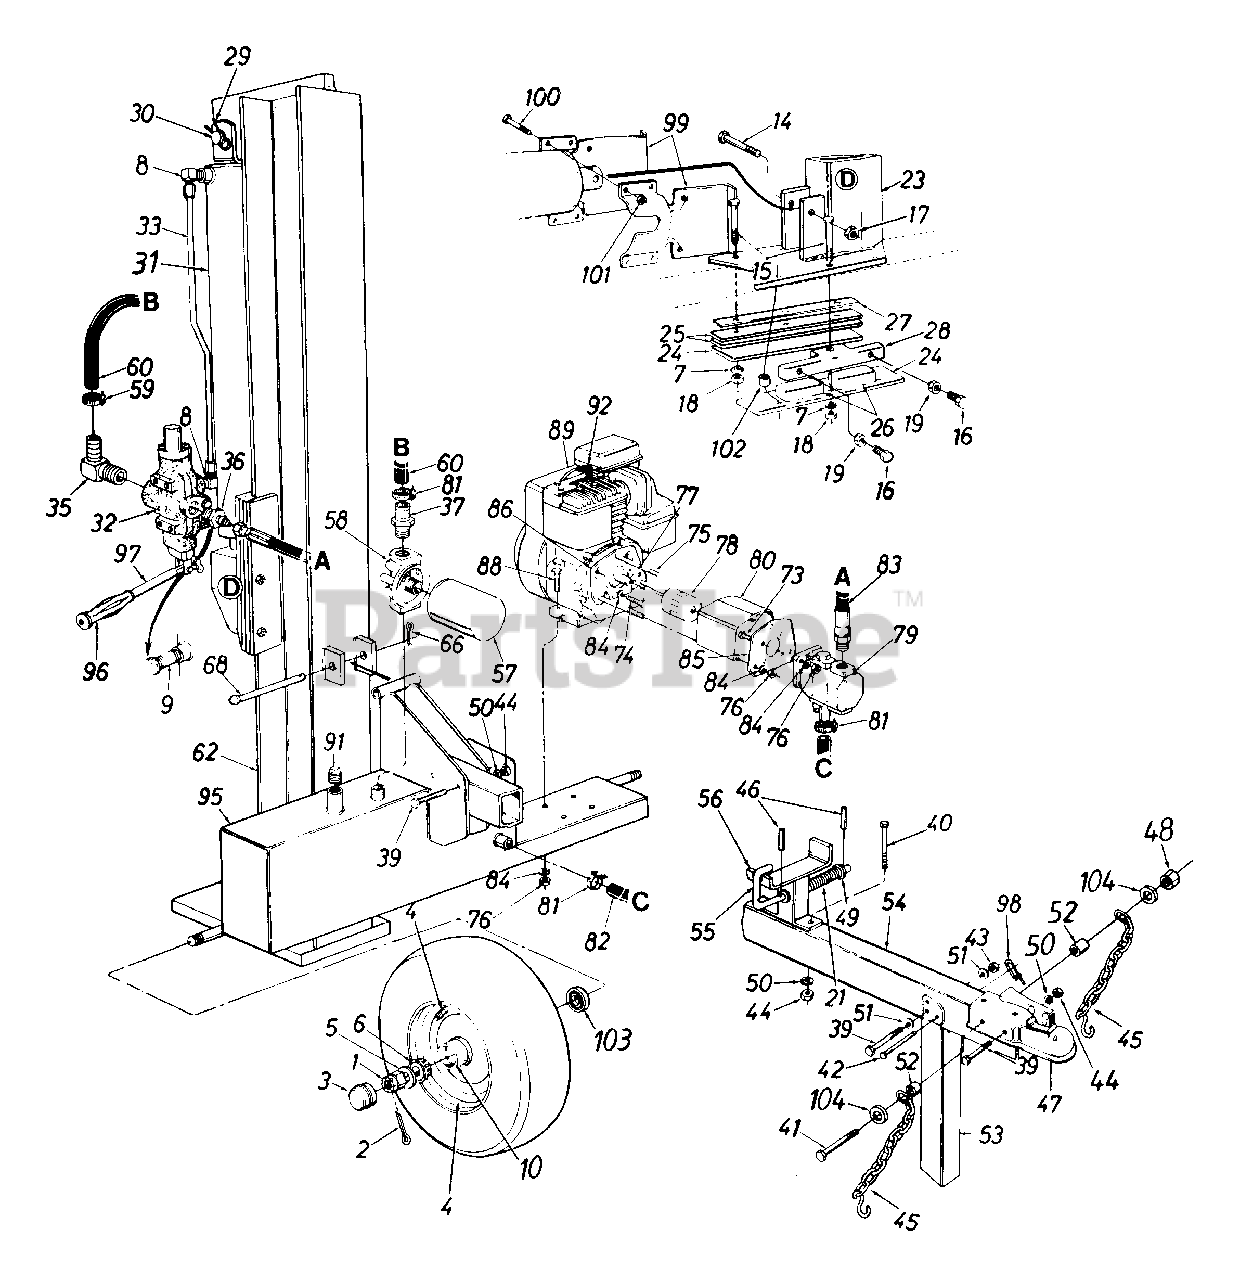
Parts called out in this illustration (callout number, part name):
1	Slotted Nut 3/4-16 Thd.
2	Cotter Pin 5/32" Dia. x 1-1/4" Lg.
3	Hub Cap
5	Fl-Wash. .76" I.D. x 1.5" O.D.
6	Bearing Cone
7	L-Wash. 1/2" I.D.
8	90° Solid Male Adapter
9	Pipe Nipple 1/2 NPT
10	Bearing Cup
14	Hex Bolt 1/2-20 x 3" Lg. (Grade 8)
15	Hex Bolt 1/2-20 x 2.75" Lg. (Grade 8)
16	Hex Bolt 3/8-24 x 1.5" Lg.
17	Hex L-Nut 1/2-20 Thd.
18	Hex Nut 1/2-20 Thd.
19	Hex Jam Nut 3/8-24 Thd. (Grade 5)
21	Comp. Spring 4" Lg.
29	External Cotter Pin
30	Cylinder Mounting Pin
31	Hydraulic Cylinder
33	Metal Pressure Tube
35	Return Elbow
36	Adapter
37	3/4" Hose Barb.
39	Hex Bolt 3/8-16 x 2.75" Lg. (Grade 8)
40	Hex Bolt 3/8-16 x 4" Lg.
41	Hex Bolt 3/8-16 x 4" Lg. (Grade 5)
42	Clevis Pin 5/16 x 2.5" Lg.
43	Hex L-Nut 3/8-16 Thd.
44	Hex Nut 3/8-16 Thd.
45	Chain - Tow Hitch
46	Roll Pin
47	Hitch Coupler
48	Hex Ctr. L-Nut 3/8-16 Thd.
49	Fl-Wash. .635" I.D. x .93" O.D.
50	L-Wash. 3/8" I.D.
51	Fl-Wash. .406" I.D. x .75" O.D.
52	Spacer 3/8" I.D. x .625" O.D.
55	Locking Rod
57	Filter Element
58	Filter Head
59	Adj. Hose Clamp
60	Return Hose 3/4" I.D. x 44" Lg.
62	Vertical Beam Ass'y.
66	Cotter Pin 1/8" Dia.
68	Hinge Pin 1/2 x 4.8" Lg.
73	Hex Bolt 5/16-24 x 1" Lg.
74	Hex Bolt 5/16-24 x .62" Lg.
75	Hex Bolt 5/16-24 x 5" Lg.
76	Hex Nut 5/16-24 Thd.
77	Sq.-Key 3/16" x .75"
78	Flexible Coupling
79	Two Volume Pump
80	Coupling Shield
81	Hose Clamp 5/8"
82	Suction Hose 3/4" I.D. x 17" Lg.
83	High Pressure Hydraulic Hose 62"
84	L-Wash. 5/16" I.D.
88	Hex Bolt 5/16-24 x 1.15" Lg.
89	Engine
91	L-Vent Pipe Plug
92	Spark Plug Boot
95	Tank Ass'y.
96	Grip
97	Control Handle
98	Spring 9 in
101	Hex L-Nut 3/8-16 Thd.
102	Spacer 1/2" I.D. x .68" Lg.
103	Bearing Seal Only
104	Fl-Wash. 3/8" I.D. x .87" O.D.
